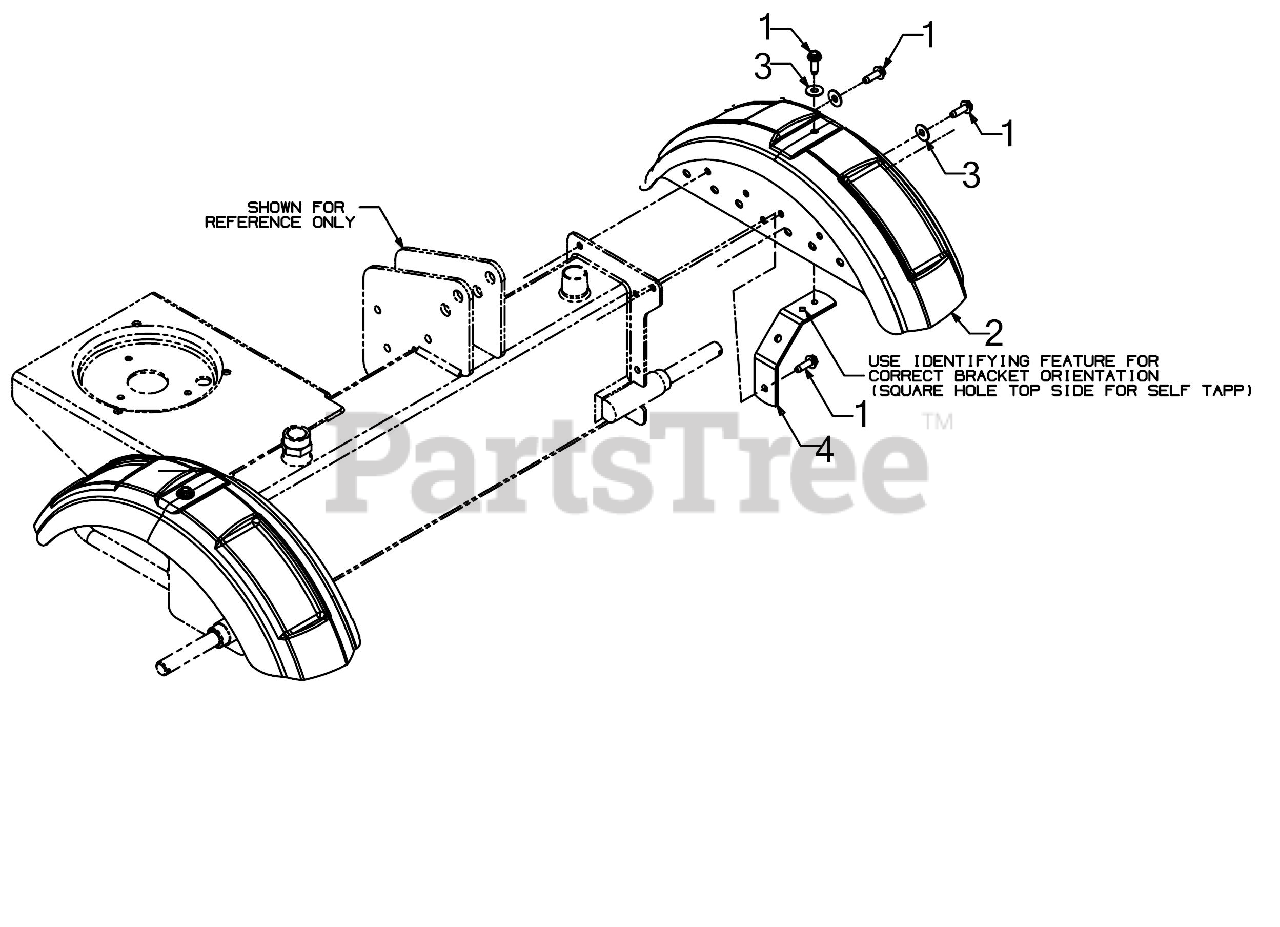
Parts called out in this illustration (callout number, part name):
1	SCREW 5/16-18 x 1.00
2	LOGSPLITTER FENDER
3	FLAT WASHER
4	MOUNTING BRACKET
